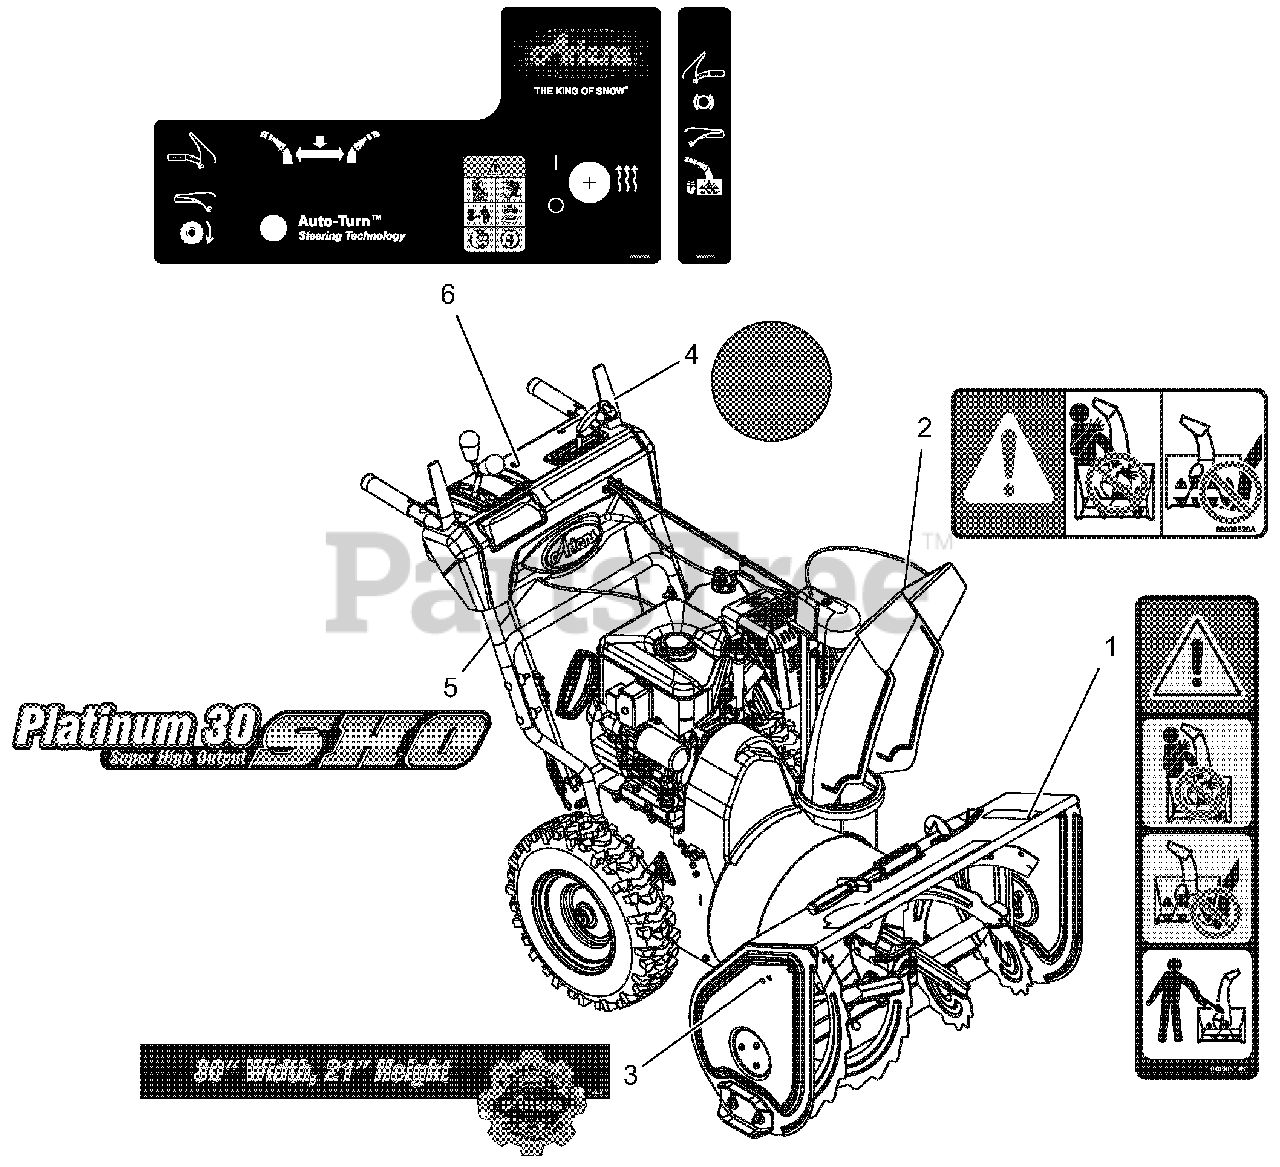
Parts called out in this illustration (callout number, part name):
1	DECAL, DANGER - ROTATING PARTS
2	DECAL, DANGER
4	DECAL,AUTODIFFERENTIAL
5	DECAL,DASH-PLATINUM 30 SHO
6	DECAL,CONTROL-LRG,QT2
